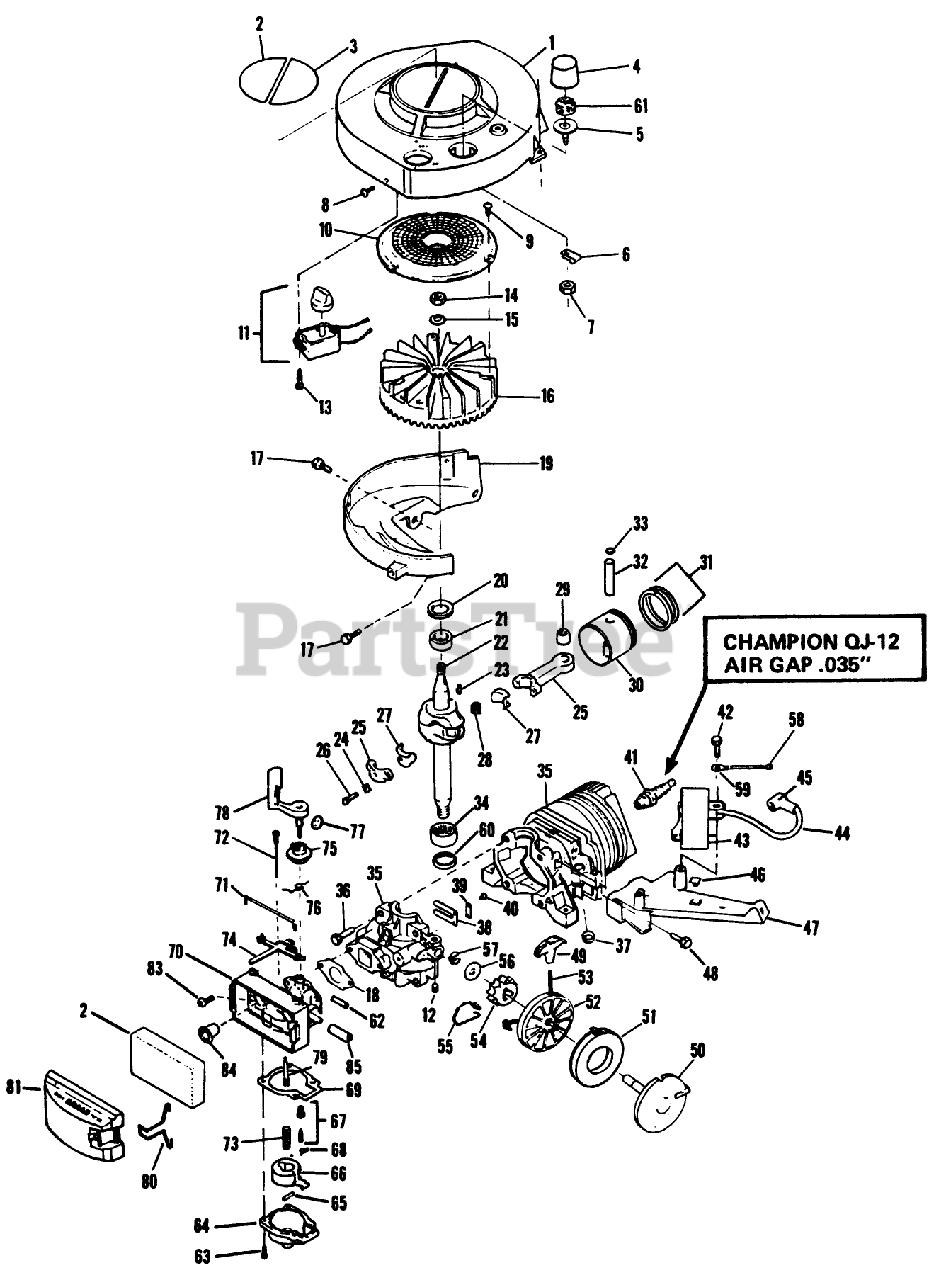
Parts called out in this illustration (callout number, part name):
2	Decal-Fuel
3	Decal-Start
7	LOCKNUT S
8	SCREW F
9	SCREW F
14	NUT
17	SCREW-SEMS
18	GASKET CARB S
21	BEARING V
23	KEY
26	SCREW
26	SCREW-HSH
27	LINER ASM
29	BEARING AY F
33	RING-RETAINING
34	BEARING V
36	SCREW S
37	PLUG-CORE VF
39	PLATE-BACKUP, REED
44	HT LEAD&COVER XEV
46	NUT-CLIP
49	HANDLE STARTER S
51	SPRING S
52	PULLEY STARTER S
55	SPRING F
56	WASHER S
59	TERMINAL S
60	SEAL-OIL
61	FILTER S
62	TUBING PRIMER S
63	SCREW-HH
70	CARB BODY S
71	RETAINER
72	NEEDLE ADJ. AY S
73	FILTER-FUEL VS
74	LEVER S
75	COLLAR-ADJUST, AIRVANE
76	SPRING,THROTTLE S
77	DISC S
78	AIR VANE&SHAFT S
80	RETAINER-COVER, FILTER
83	SCREW S
